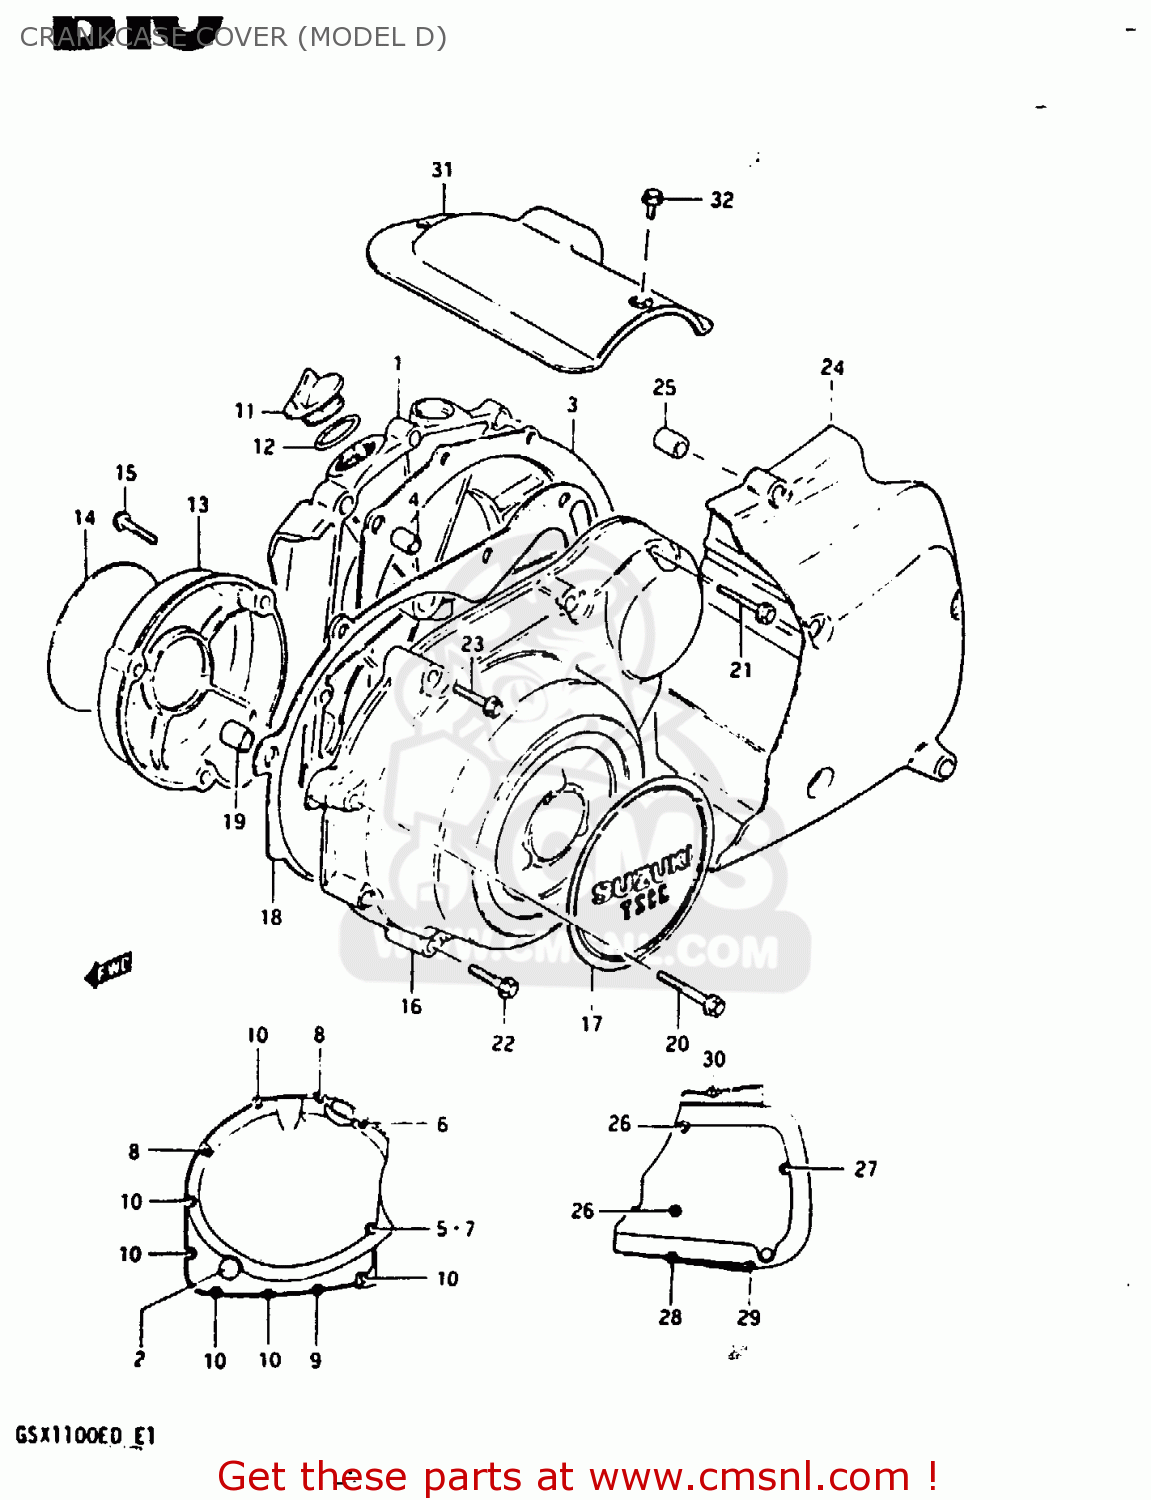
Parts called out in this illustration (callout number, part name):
1	COVER,CLUTCH
2	LENS,OIL LEVEL CHECK
3	GASKET,CLUTCH COVER (MCA)
4	PIN
5	GASKET (NAS)
6	BOLT (6X40)
7	BOLT (6X35)
8	BOLT (6*30)
9	BOLT (6X25)
10	BOLT 6X20
11	CAP
12	O RING(D:2.2,ID:32)
13	COVER,CONTACT BREAKER
14	EMBLEM
15	BOLT (5X30)
16	COVER,MAGNETO
17	EMBLEM,MAGNETO COVER
18	GASKET,MAGNETO COVER (MCA)
19	PIN
20	BOLT (6X45)
21	BOLT (6X40)
22	BOLT (6X35)
23	BOLT (6X30)
24	COVER,ENGINE SPROCKET
25	PIN
26	BOLT (6X95)
27	BOLT (6X85)
28	BOLT (6X70)
29	BOLT (6X55)
30	BOLT (6*30)
31	COVER,STARTER MOTOR
32	BOLT (5X8)
